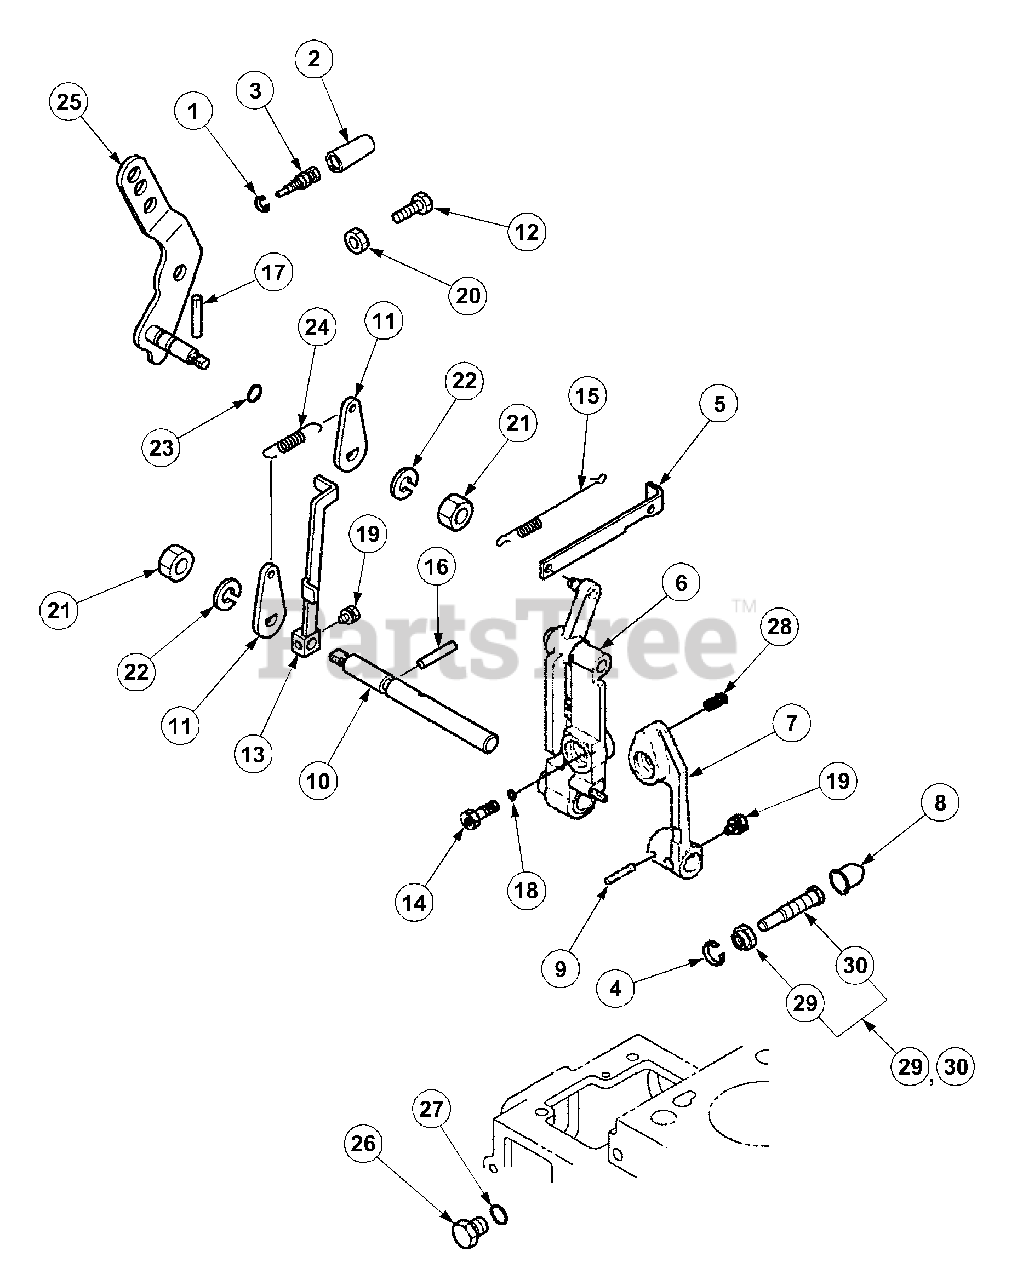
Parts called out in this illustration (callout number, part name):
4	C-Ring,Torque
6	Lever Assy,Governor
7	Lever,Tension
9	Pin,Spring
10	Shaft,Governor
11	Lever,Governor
12	Bolt,Low Idle
14	Spring Assy,Angle
15	Spring,Tie-Rod
16	Pin,Grooved
17	Pin,Grooved
19	Bolt,w/Washer
22	Washer,Spring
24	Spring,Governor
25	Lever Assy,Speed
26	Bolt,Idle Sub
29	Nut,Torque Set
30	Screw,Pack Set
